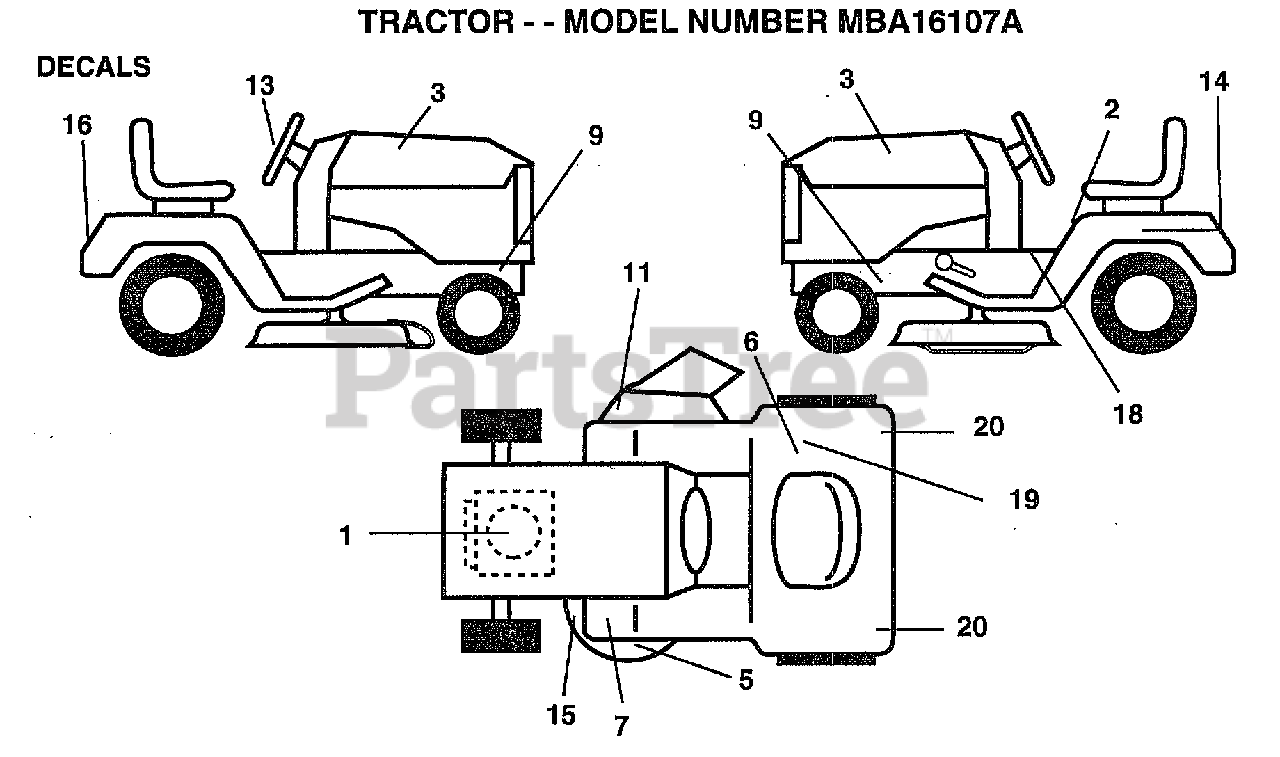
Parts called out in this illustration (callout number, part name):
2	DECAL.READ.O.MANU
3	DECAL, NAMEPLATES
5	"DECAL,ENVIRO DECK"
6	DECAL.EURO.ST.CE.
7	DECAL-BRAKE/CLUTC
9	"DECAL CHASSIS,HOT"
11	DECAL.DANGER.CUTF
13	DECAL.WHL.STEERING
14	DECAL.BATRY.3-3908
15	"DECAL-SCHEM,BELT"
16	DECAL.FENDER
17	"PAD-FOOTREST,SQ"
18	DECAL BRAK PARK
20	REFLECTOR-TAIL YT
